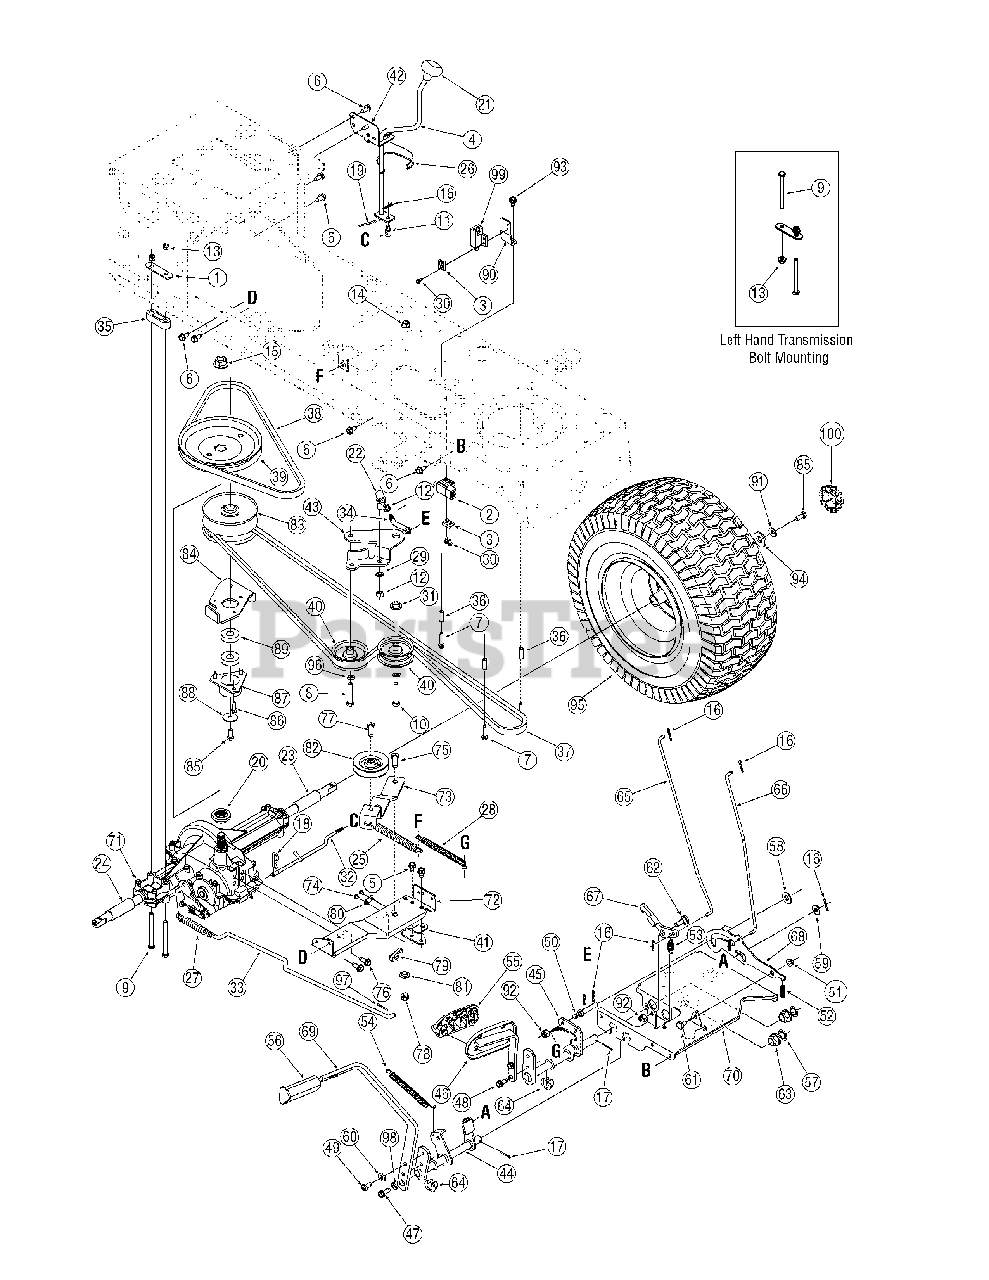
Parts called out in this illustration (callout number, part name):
1	Mounting Bracket, Transaxle
2	Switch, Interlock
3	Plate, Switch
4	Lever Assembly, Shift
5	Screw, 5/16-18, 0.500
6	Screw, 5/16-12, 0.750
7	Screw, 1/4-20, 1.250
8	Screw, Sems, 3/8-16, 1.500
9	Screw, 5/16-18, 3.50, Gr5
10	Screw, 3/8-16, 2.00, Gr5
11	Adjustment Ferrule 1/4-20 x 1
12	Nut, Hex, 3/8-24, Gr5
13	Nut, Flange Lock, 5/16-18, GrF
14	Nut, Flange Lock, 3/8-16, GrF
15	Nut, Flange, 9/16-18, Gr2
16	Pin, Cotter,.072 Dia. x 1.13
17	Pin, Cotter, 3/32, 1.0
18	Cotter Pin, Internal,.125 Dia.
19	Pin, Cotter, 1/8 x 1.25
20	Pulley Hub, 5/8 Spline
21	Knob, Shift
22	Ball Joint
23	Sleeve,.758 x.821 x 3.3125
24	Sleeve,.758 x.821 x 2.4375
25	Spring, Extension,.62 Dia x 6.12
26	Spring Clip, Shifter
27	Spring, Extension,.59 OD x 4.00
28	Spring, Extension,.50 Dia x 6.37
29	Washer, Lock, 3/8
30	Screw, #10-16,.50
31	Spacer, Shoulder, 1.00 x.38 x.38
32	Rod, Shift
33	Rod, Brake
34	Idler Rod, Adjustable, 3/8
35	Spacer,.68
36	Spacer,.260 x.372 x 1.030
37	Belt, V-Type
38	Belt, V-Type
39	Pulley, V-Type, 7.25 Dia.
40	Idler Pulley, Flat 2.75 OD
41	Bracket, Shift
42	Bracket, Shift, F-N-R
44	Control Assembly, Brake
45	Control Assembly, Speed
46	Pedal Assembly
47	Screw, 5/16-18, 0.875
48	Screw,5/16-18, 0.750
49	Screw, 5/16-18, 0.750
50	Pin, 3/8-16 x 2.68
51	Nut, Flange Lock, 5/16-18, Gr5
52	Spring, Compression.,.405 x 1.17
53	Spring, Extension,.50 OD x 1.41
54	Spring, Extension,.50 OD x 6.37
56	Pad, Brake
57	Washer, Flat,.64 x 1.24 x.06, HT
58	Washer, Flat,.385 x.870 x.092
59	Washer, Flat,.406 x.875 x.059
60	Washer, Flat,.344 x.750 x.120
61	Screw, Shoulder.437 Dia x.162
62	Screw, Shoulder,.50 x.27 Lg
63	Bearing, Hex Flange
64	Split Bearing, Hex Flange
65	Rod, Brake Lock
66	Rod, Cruise Control
67	Latch, Cruise Control
68	Bracket, Lockout
71	Transmission, Single Speed
72	Bracket Assembly, Torque
73	Bracket, Idler
74	Screw, #8-18 x.50
75	Screw, 3/8-16, 1.00
76	Screw, 5/16-18,.625
77	Screw, 3/8-16, 1.250
78	Nut, Lock, 3/8-16, Nylon
79	Switch Spring, Short
80	Plate, Insulator
81	Spacer, Shoulder
82	Pulley, V-Type, 3.06
83	Pulley Ass’y, Variable Speed
84	Bracket, Pulley
85	Screw, 5/16-24,.750
86	Screw, 1/4-20,.625
87	Cup, Bearing
88	Washer, Flat
89	Ball Bearing
92	Nut, Flange Lock, 3/8-16,
93	Screw, 1/4-20 x.500 GrF
94	Flat Washer,.350 x 1.59 x .062
96	Flat Washer, .407 x .812
97	Pin, Cotter, 3/32 x .750
98	Lock Washer, 5/16
99	Switch
100	Hub Cap
